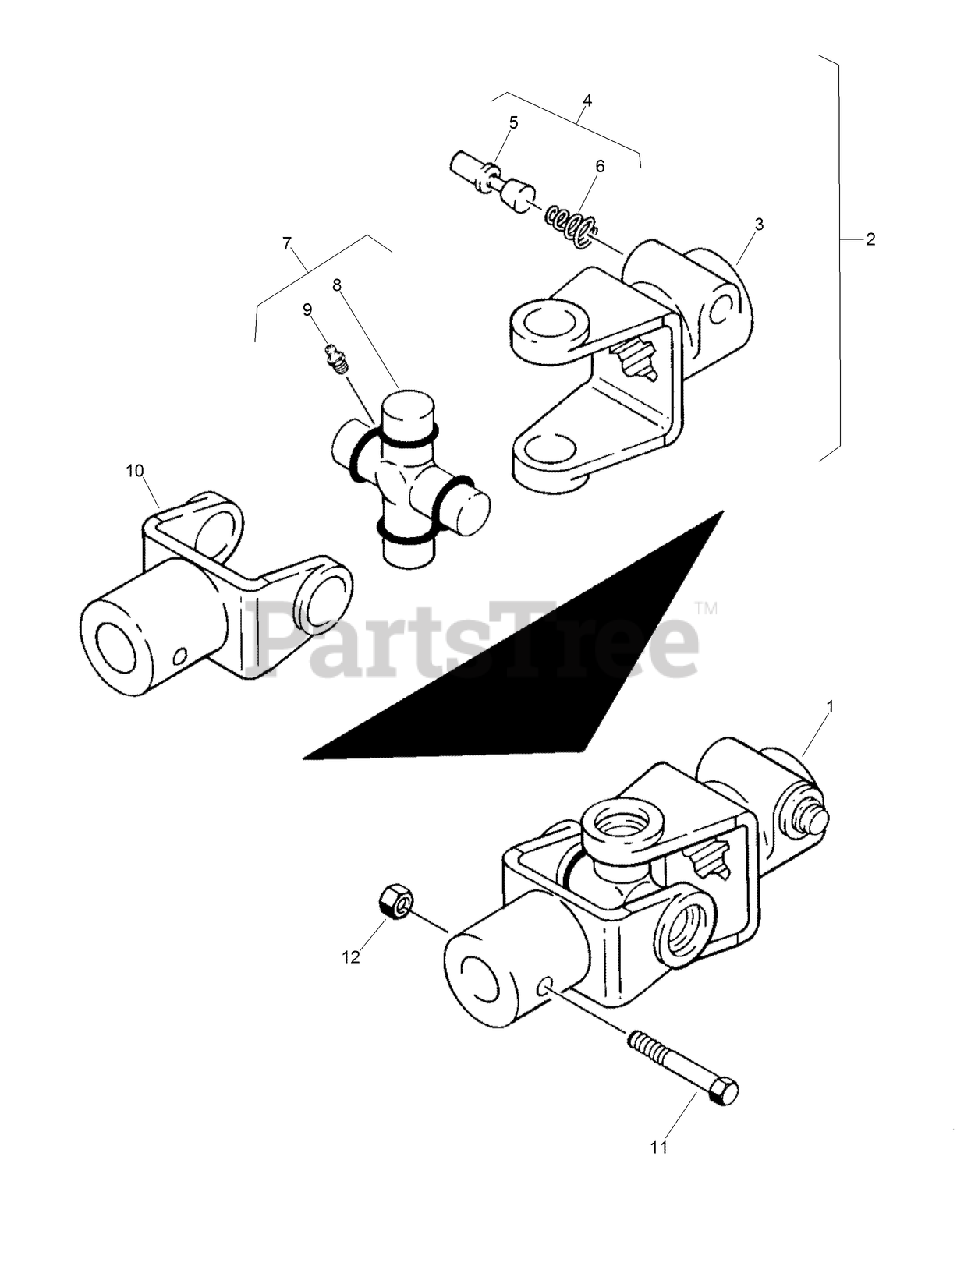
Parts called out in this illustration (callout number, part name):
1	U-JOINT ASM
2	YOKE ASM-splined, mounts to gearbox
3	YOKE-splined, mounts to gearbox
4	KIT-universal joint retaining
5	PIN-retaining
6	SPRING-special
7	CROSS ASM-universal joint
8	CROSS-U-joint
9	FITTING-grease, straight, 1/4-28 taper x 15/16 inch
10	YOKE-boring attachments
11	BOLT-hex, 3/8 NC x 2-1/2 inch, grade 2
12	NUT
